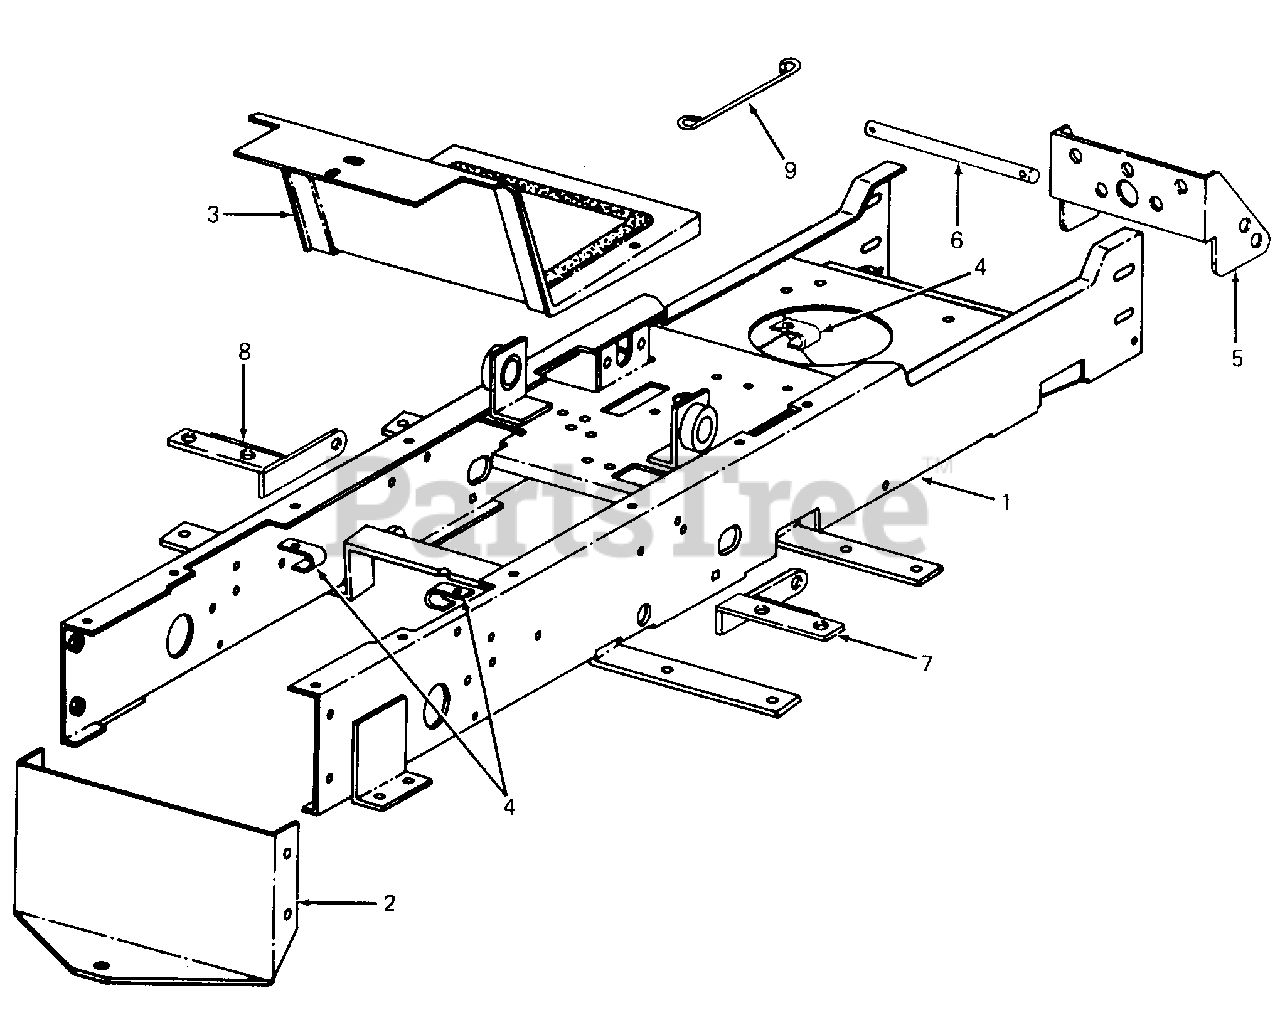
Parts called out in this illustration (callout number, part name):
3	Cover w/Graphic
4	Clip, Cable
5	Front Mower Support
6	Deck Support Rod
7	Rear Deck Bracket Assy, RH
8	Rear Deck Bracket Assy, LH
9	Link Retaining Rod
